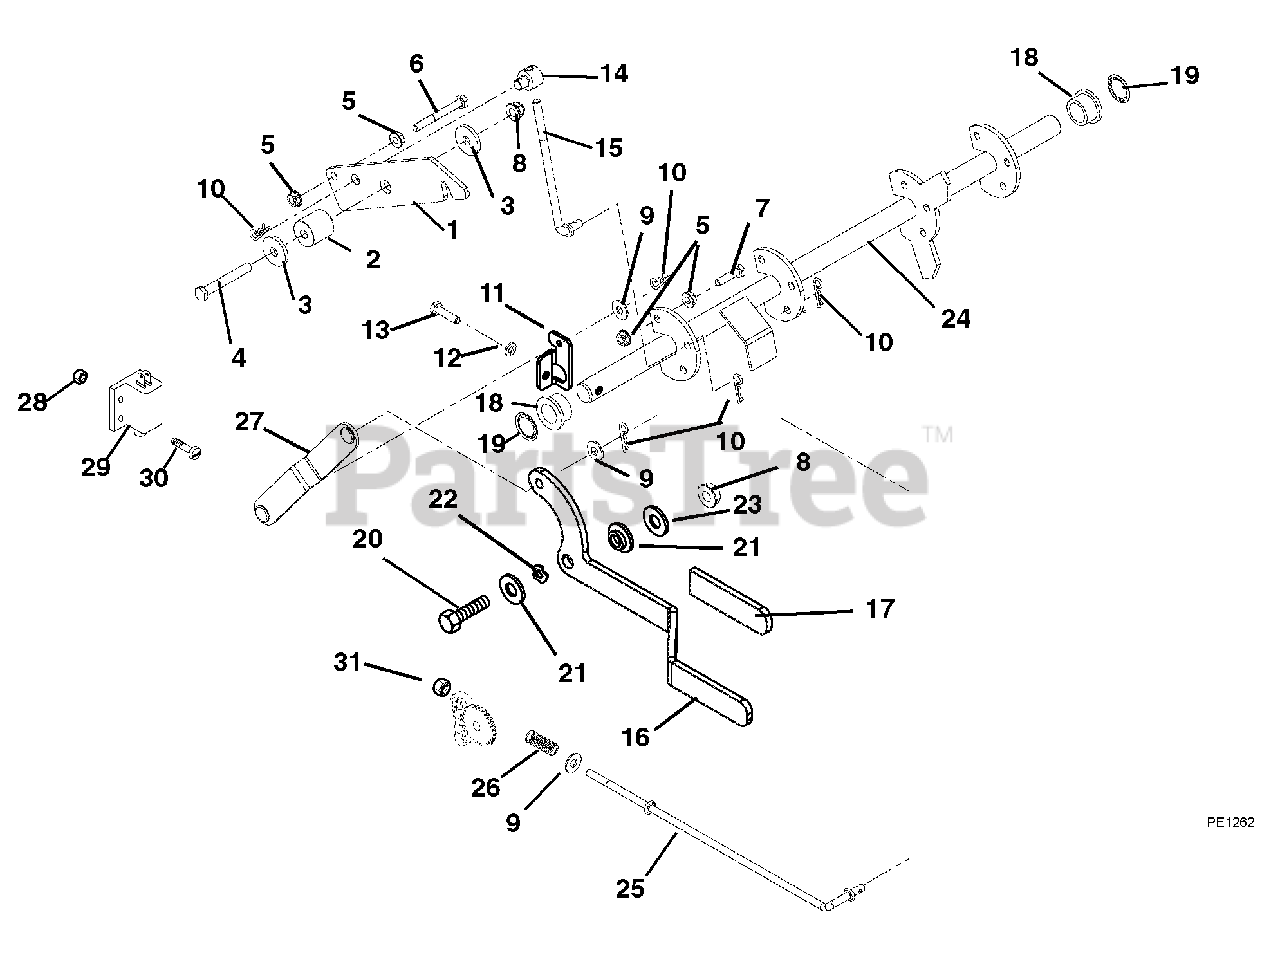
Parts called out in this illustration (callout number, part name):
1	LATCH, NEUTRAL
2	SPCR, FLG .32X.49X.192X1.00
3	WSHR-FL-STL .344X1.125X.135
4	@BLT-HEX .31-18X2.25 GR5 YWZC
5	@NUT-SPNLK-FLG .25-20 YWZC
6	@BLT-HEX .25-20X2.25 GR5 YWZC
7	@BLT-HEX .25-20X1.00 GR5 YWZC
8	@NUT-LK-NYL-FLG .31-18 YWZC
9	@WSHR-FL-STL.312X.734X.065 YWZ
10	PIN-HAIR INT .08X.18X1.18 YWZC
11	CRANK, PARKING BRAKE
12	@WSHR-LK .25X.062 REG YWZC
13	@BLT-HEX .25-20X1.00 GR5 YWZC
14	TRUNNION, BRAKE .31-18 UNC
15	BRAKE LINK
16	HANDLE, PARKING BRAKE
17	GRIP,HANDLE
18	BSHG-FLG .750X1.000X.625X1.250
19	NUT, PUSH -.75" SHAFT
20	@BLT-HEX .31-18X1.75 GR5 YWZC
21	BSHG-FLG .325X.501X.250X1.120
22	WSHR-WAVE .50X.75X.015 .13FRHT
23	WSHR-FL-STL .328X.87X.179 YWZC
24	WELDMENT, BRAKE SHAFT
25	ROD - BRAKE
26	SG-COMP .045X.50X1.187
27	WELDMENT, BRAKE LINK
28	@NUT-LK-NYL 10-24 W/INSRT YWZC
29	SWITCH- DOUBLE POLE N.O./N.O.
30	@SCR-MCH 10-24X.75 HWH YWZC
31	@NUT-LK-NYL .250-20 YWZC
32	KIT, 40" DECK (1540)
